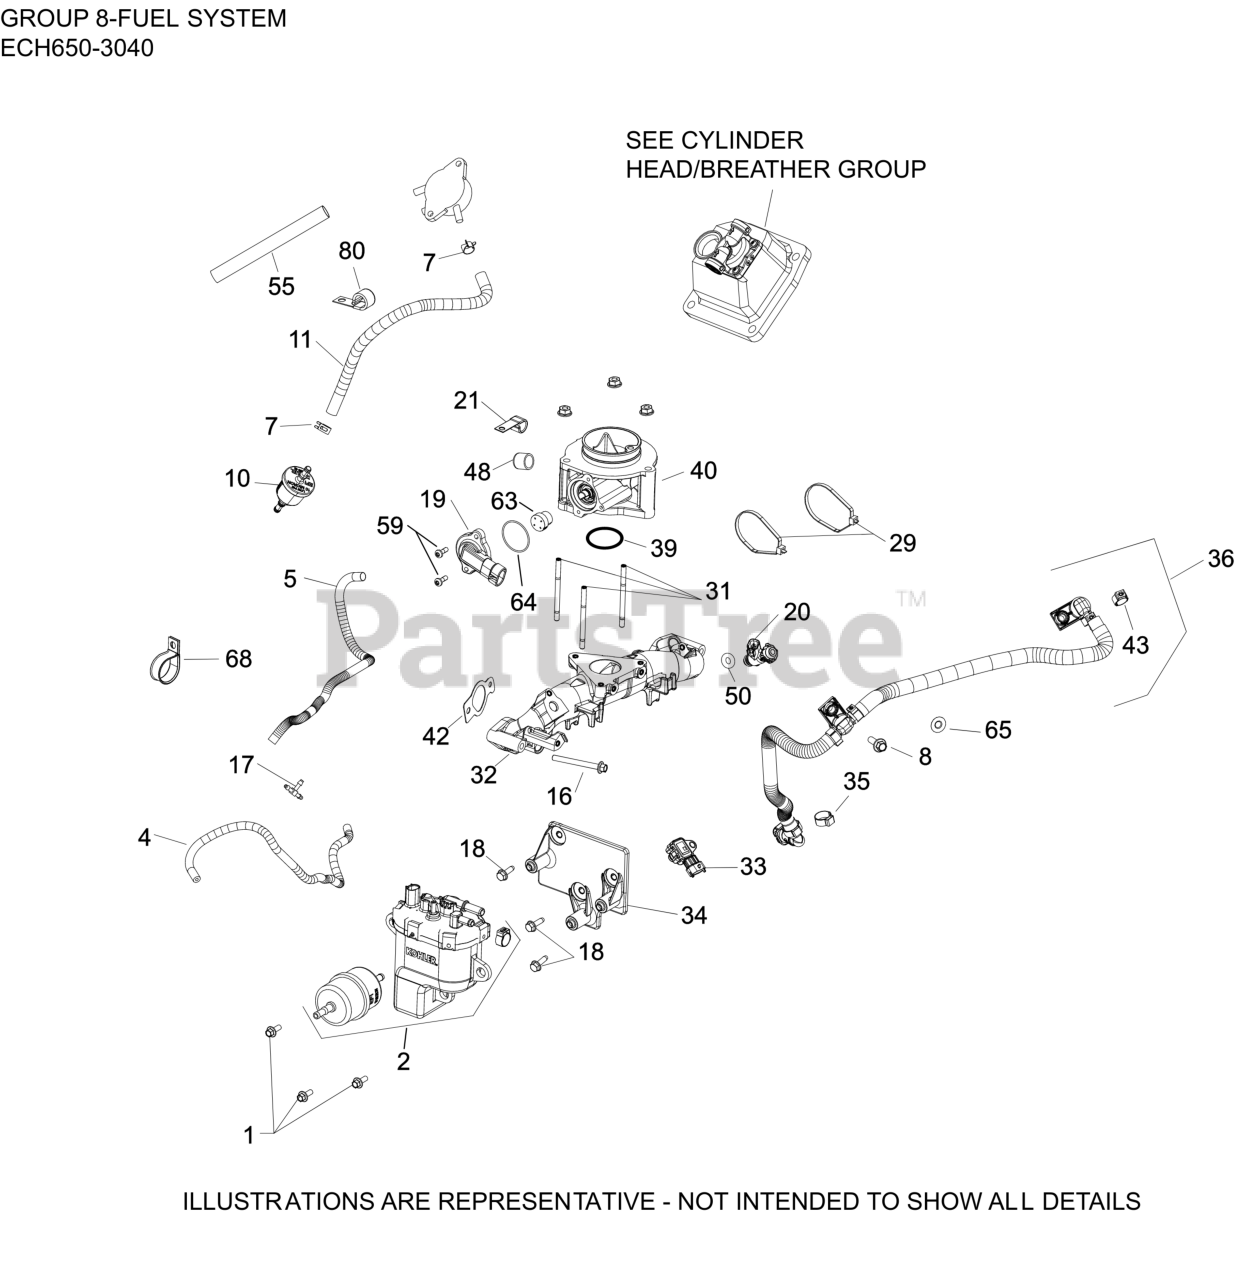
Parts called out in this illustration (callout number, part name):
1	SCREW, FLG M6X1.0X16
2	KIT, FUEL PUMP MODULE
4	HOSE, EVAPORATIVE (15.0)
5	SLEEVE, ANTI-ABRASION
7	CLAMP, HOSE (KM)-USE 25 237 31-S
8	SCREW, FLG M6x1.0x20
10	FILTER, FUEL
11	HOSE,LW PERM.FUEL 24.00"-USE 25 111 81-S
16	SCREW, FLG M6X1.0X60
17	TEE CONNECTOR
18	SCREW, THREAD FORMING
19	SENSOR, THROTTLE POSITION
20	INJECTOR, FUEL
21	CLIP, CABLE
31	STUD,M6X1.0X84
32	KIT, MANIFOLD
33	SENSOR, T-MAP
34	BAFFLE, FUEL MODULE
35	CLAMP, HOSE
36	FUEL HOSE ASSEMBLY,ECH680-ECH749
39	O-RING, THROTTLE BODY
40	BODY, THROTTLE ASM W/ PIN (30)
42	KIT, INTAKE MANIFOLD GASKET
43	CLAMP, OETIKER
48	CAP, MASKING
50	KIT, FUEL INJECTOR O-RING
55	SLEEVE, ANTI ABRASION-USE 25 431 12-S
63	MAGNET ASSEMBLY, TPS
64	O-RING, TPS SENSOR
65	CLIP, RETAINER
68	CLAMP, INSULATED
80	CLIP, CABLE (KM)
